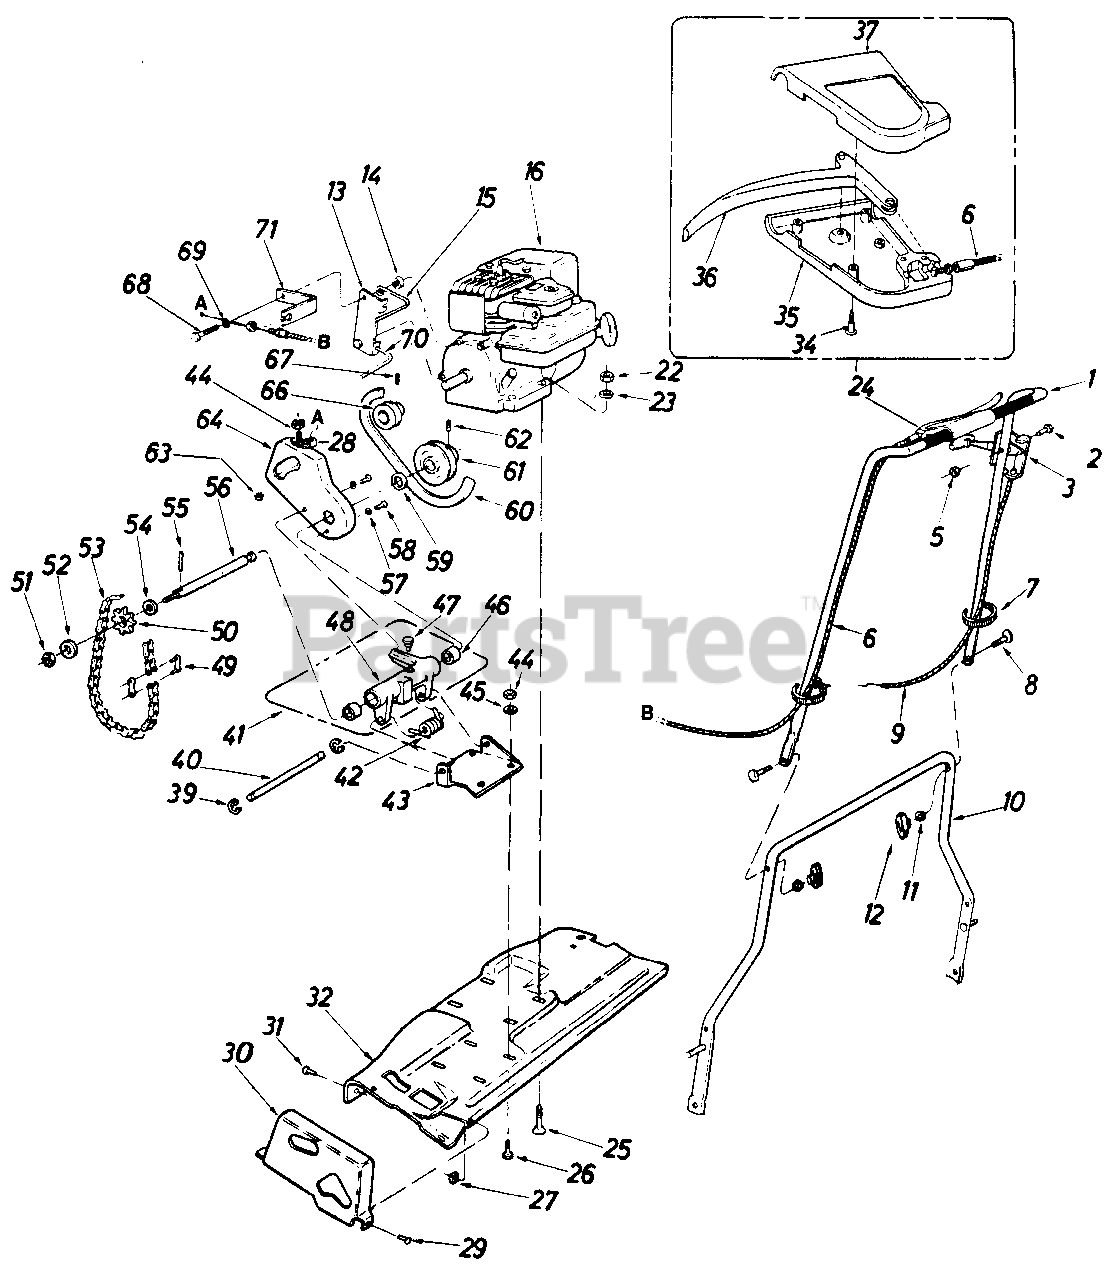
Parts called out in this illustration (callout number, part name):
1	Upper Handle Ass'y.
2	3 Rd. Hd. Scr. 1/4-20 x 1.88" Lg.
3	Throttle Control Ass'y.
5	Capped Wash. Z-Nut
6	Clutch Control Cable
7	Cable Tie
8	Special Scr. 5/16-18 x 1.75" Lg.
9	Throtle Cable
10	Lower Handle Ass'y.
11	L-Wash. 5/16
12	Handle Knob
13	Belt Keeper Brkt.
14	Spacer
15	Belt Keeper-Upper
16	Engine
22	Hex Nut 5/6-18 Thd.
23	L-Wash. 5/16
24	Clutch Control Ass'y.
25	Carriage Bolt 5/16-18 x .625" Lg.
26	Scr. 1/4-20 x .625" Lg.
27	Hex L-Nut 10-32 Thd.
28	Clevis Lanyard Fiting
29	Ph. Hd. Scr. 10-32 x .375" Lg.
30	Chain Guard
31	Hex Sems Scr. 5/16-24 x .50 Lg.*
34	Sloted Oval Self-Tap Scr. #10 x .87" Lg.
35	Rear Control Cover
36	Lever Clutch Control
37	Front Cover Control
39	Retaining Ring
41	Jack Shaft Hsg. and Brg. Ass'y.
42	Spring
43	Bracket
44	Hex Nut 1/4-20 Thd.
45	1/4 Split L-Wash.
46	Bearing
47	Oiler
48	Jack Shaft Hsg.
49	Connector Link
50	Sprocket
51	Hex Jam Nut 5/16-24
52	Washer
53	Chain
54	Wash. 5/8 x 15/16
56	Jack Shaft
57	Washer
58	Ph. Hd. Scr. 10-32 x .50 Lg.
59	Wash. 5/8 x 15/16
60	V" Belt
61	Pulley Ass'y.
62	Roll Pin
63	Hex Nut 1/4-20 Thd.
64	Belt Guard Ass'y.
66	Pulley
67	Set Scr. 5/16-24 x 7/32" Lg.
68	Ph. Hd. Scr. 1/4-20 x 1.75" Lg.
69	L-Wash. 1/4" Scr.
70	Belt Keeper-Lower
71	Clutch Cable Bracket
